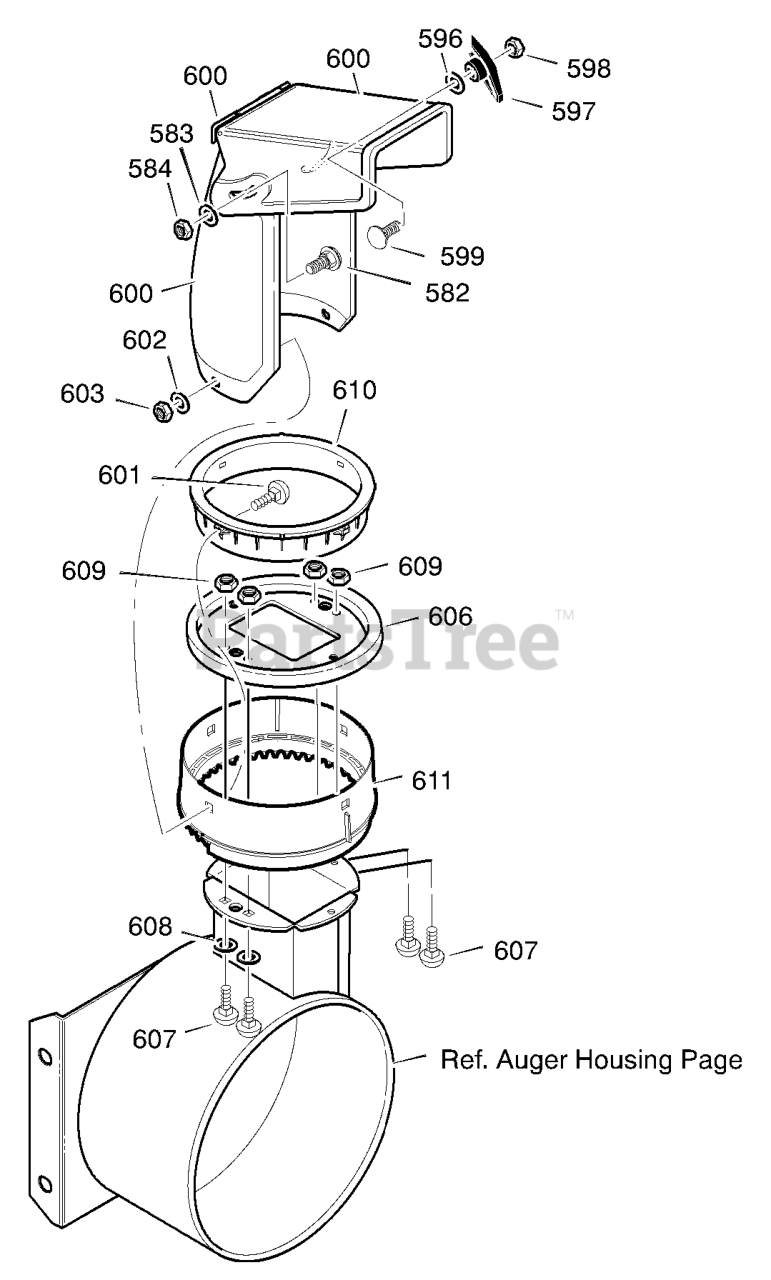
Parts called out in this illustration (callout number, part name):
582	SCREW, 5/16-18 x 0.75
583	WASHER, FLAT
584	NUT, 5/16-18 REGHEXCTRLK
596	WASHER
597	KNOB, T 3.00
598	NUT, 5/16-18 REGHEX
599	BOLT, 5/16-18X1.125
600	CHUTE ASSEMBLY
601	BOLT, 5/16-18 X1.00
602	WASHER, FLAT
603	NUT, 5/16-18 HEXNYL
606	CHUTE COLLAR
607	SCREW, 1/4-20 X 1.00
608	WASHER, FLAT
609	NUT, 1/4-20 HEX NYLOCK
610	RETAINER RING INNER
611	RETAINER RING OUTER
